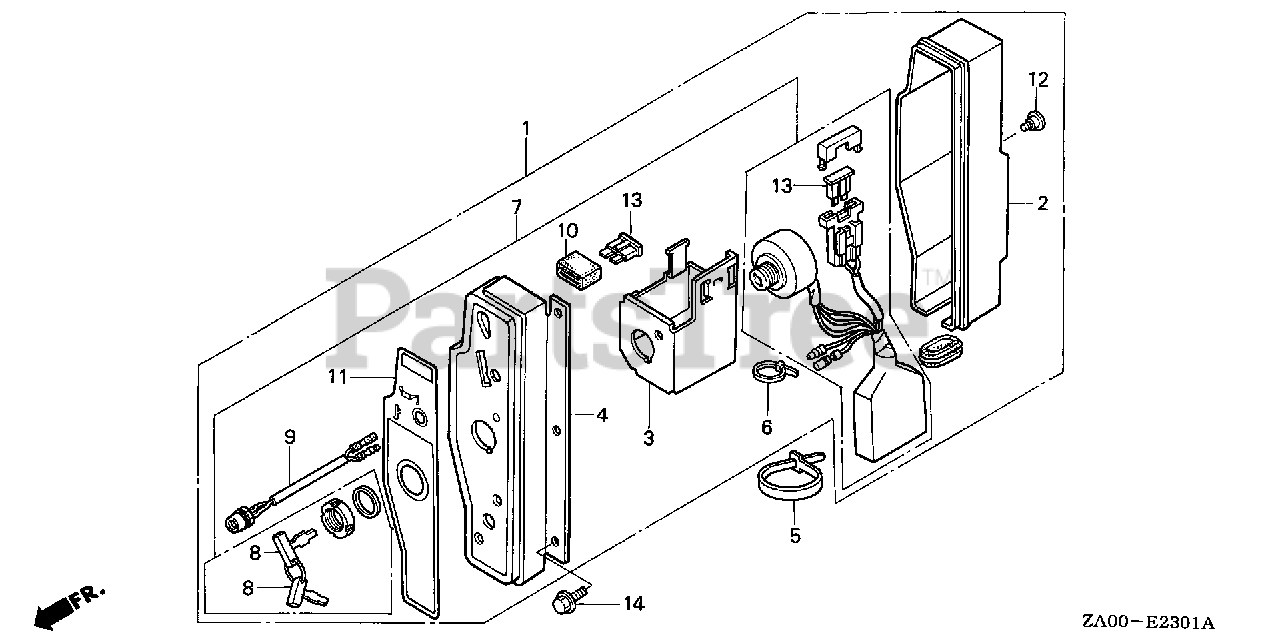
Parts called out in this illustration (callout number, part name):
1	BOX ASSY., CONTROL (10A)
2	CASE, CONTROL
3	BRACKET, CASE MOUNTING
4	PANEL ASSY., CONTROL
5	BAND, WIRE Use up to Frame SN 1001879.
6	BAND
7	SWITCH ASSY., COMBINATION (Honda Code 4337861). (10A)
8	KEY
9	L.E.D. ASSY. (RED)
10	SUSPENSION, TURN SIGNAL RELAY (Honda Code 1491299). (DENSO)
11	PLATE, CONTROL INDICATION (10A)
12	SCREW, SPECIAL (6X12)
13	FUSE, BLADE (15A)
14	BOLT, FLANGE (6X8)
